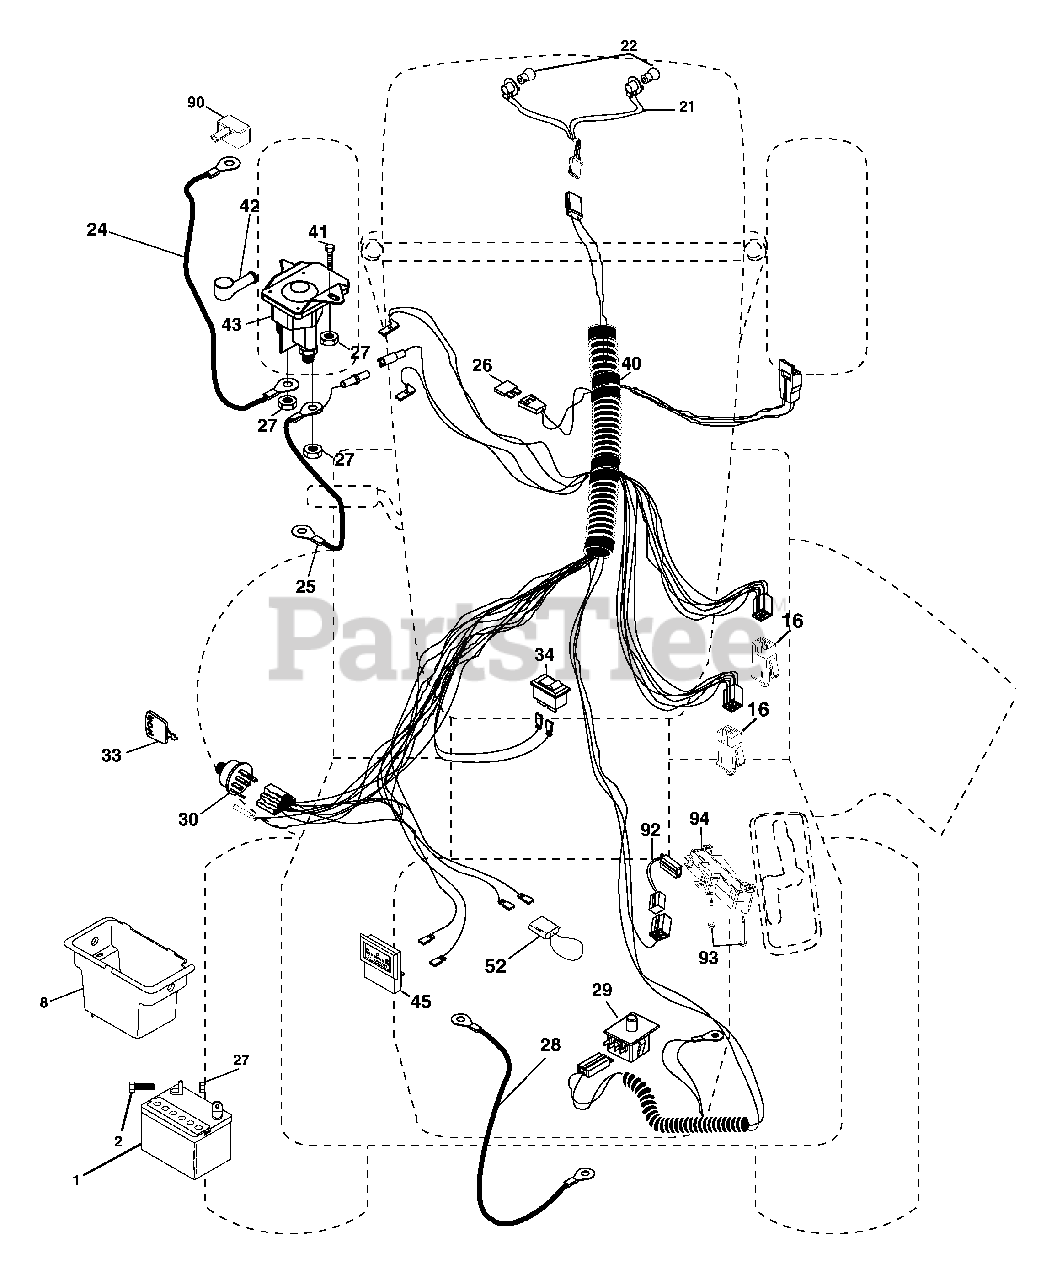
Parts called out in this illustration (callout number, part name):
1	Battery
2	Bolt Hex Hd 1/4-20 unc x 3/4
8	Box Battery
16	Switch Interlock
21	Harness Socket Light
22	Bulb, Light # 1156
24	Cable Battery
25	Cable Battery 6 Ga. Red w/16 wire 44"
26	Fuse
27	Nut Keps Hex 1/4-20 unc
28	Cable Ground 12" Blk 6 Ga.
29	Switch Seat
30	Switch Ign
33	Key Ign Molded Generic
34	Switch Light/Reset
40	Harness Ign
41	Bolt Fin Hex 1/4-20 unc x 1/2
42	Cover Terminal Red
43	Solenoid
45	Ammeter
52	Protection Loop
90	Cover Terminal
92	Harness Pigtail Reverse Switch
93	Screw Plastite 10-1/4 x 2.0
94	Module Reverse ROS
